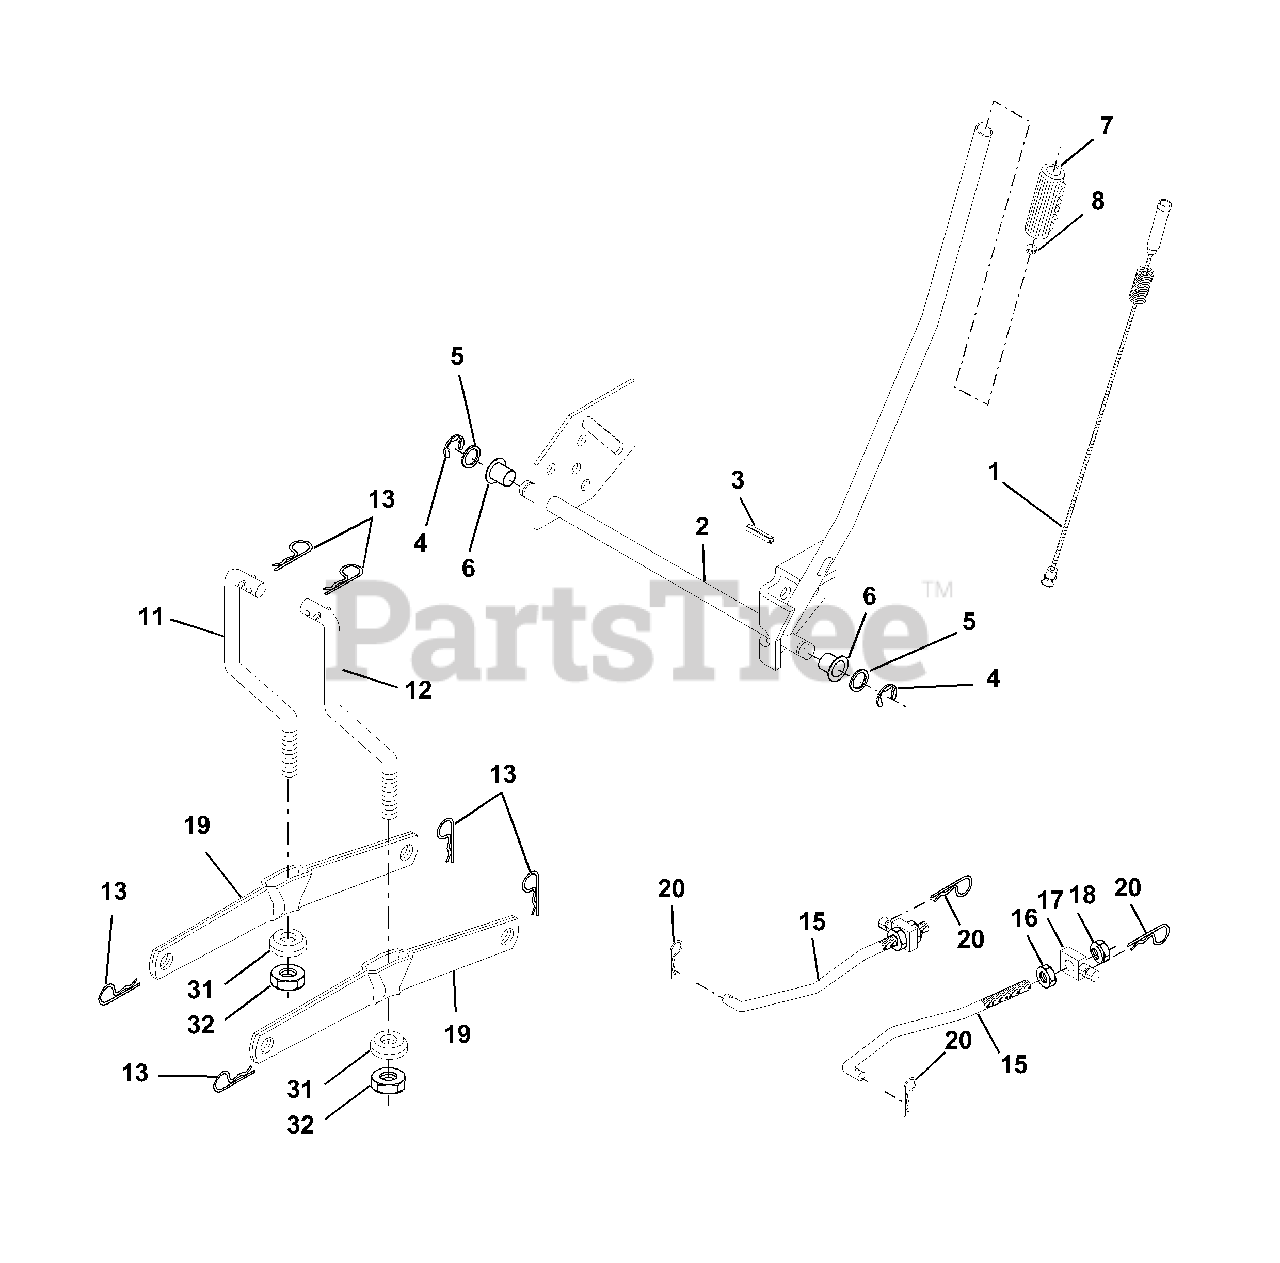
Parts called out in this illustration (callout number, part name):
1	Wire Asm Inner/Sprg w/plunger
2	Shaft Asm Lift RH
3	Pin Groove 1 500 Zinc
4	E Ring #5133-62
5	Washer 21/32 X 1 X 21 Ga
6	Bearing Nylon Blk 629 Id
7	Grip Handle Bicycle Matte Blk
8	Button Plunger Black
11	Link Lift LH Fixed Length
12	Link Lift RH Fixed Length
13	Retainer Spring
15	Link Front
16	Nut Jam Hex 1/2-13 Unc
17	Trunnion Blk Zinc
18	Nut Lockw/Wsh 1/2-13 Unc
19	Arm Suspension Rear
20	Retainer, Spring
31	Bearing Pvt Lift Spherical
32	Nut Crownlock 3/8-24
